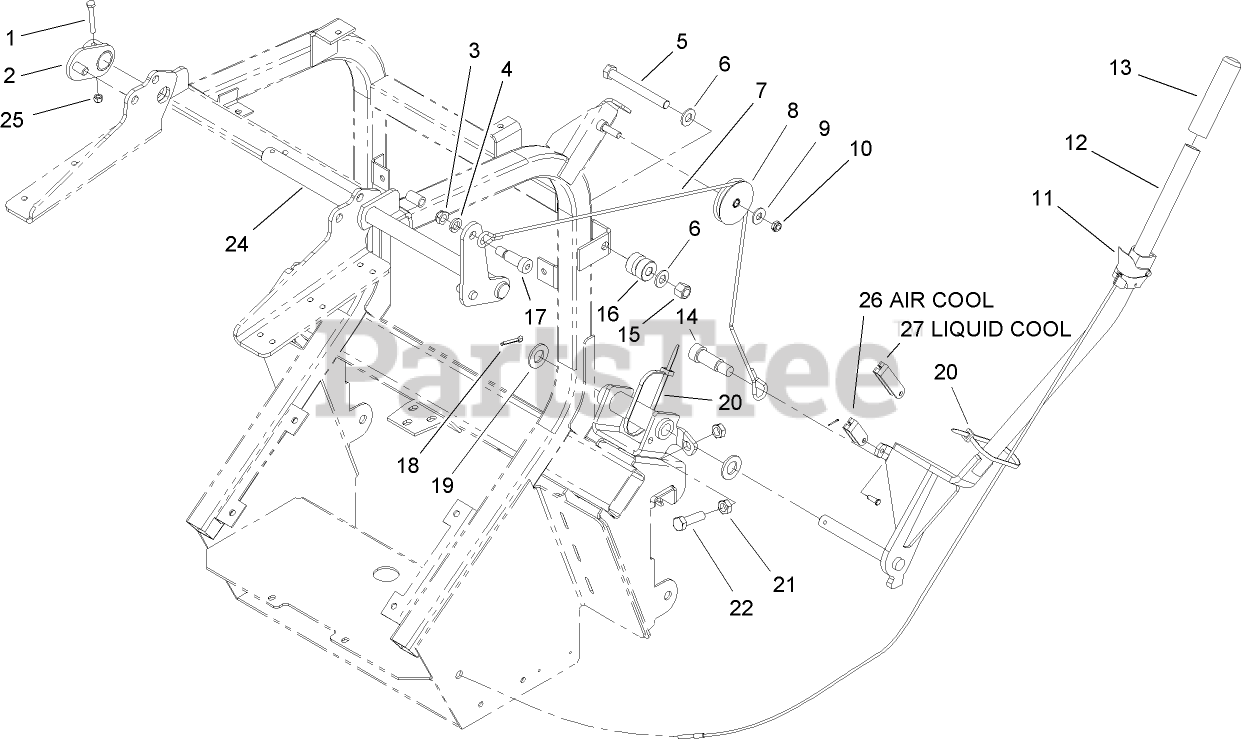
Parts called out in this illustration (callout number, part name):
1	SCREW-HH
2	SHORT LINKAGE ASM
3	NUT-LOCK, NI
4	WASHER-LOCK
5	SCREW-HH
6	WASHER-FLAT
7	CABLE-DOOR
8	PULLEY ASM
9	WASHER-FLAT
10	NUT-LOCK, NI
11	LATCH-CABLE, DUMP
12	DUMP ARM ASM
13	GRIP-FOAM
14	SCREW-SHOULDER
15	NUT-LOCK, NI
16	ROLLER-CABLE
17	SCREW-SHOULDER
18	PIN-COTTER
19	WASHER-FLAT
20	TIE-CABLE
21	NUT-JAM
22	SCREW-HH
24	LONG LINKAGE ASM
25	NUT-LOCK, NI
26	CLEVIS-SHORT
27	CLEVIS-LONG
